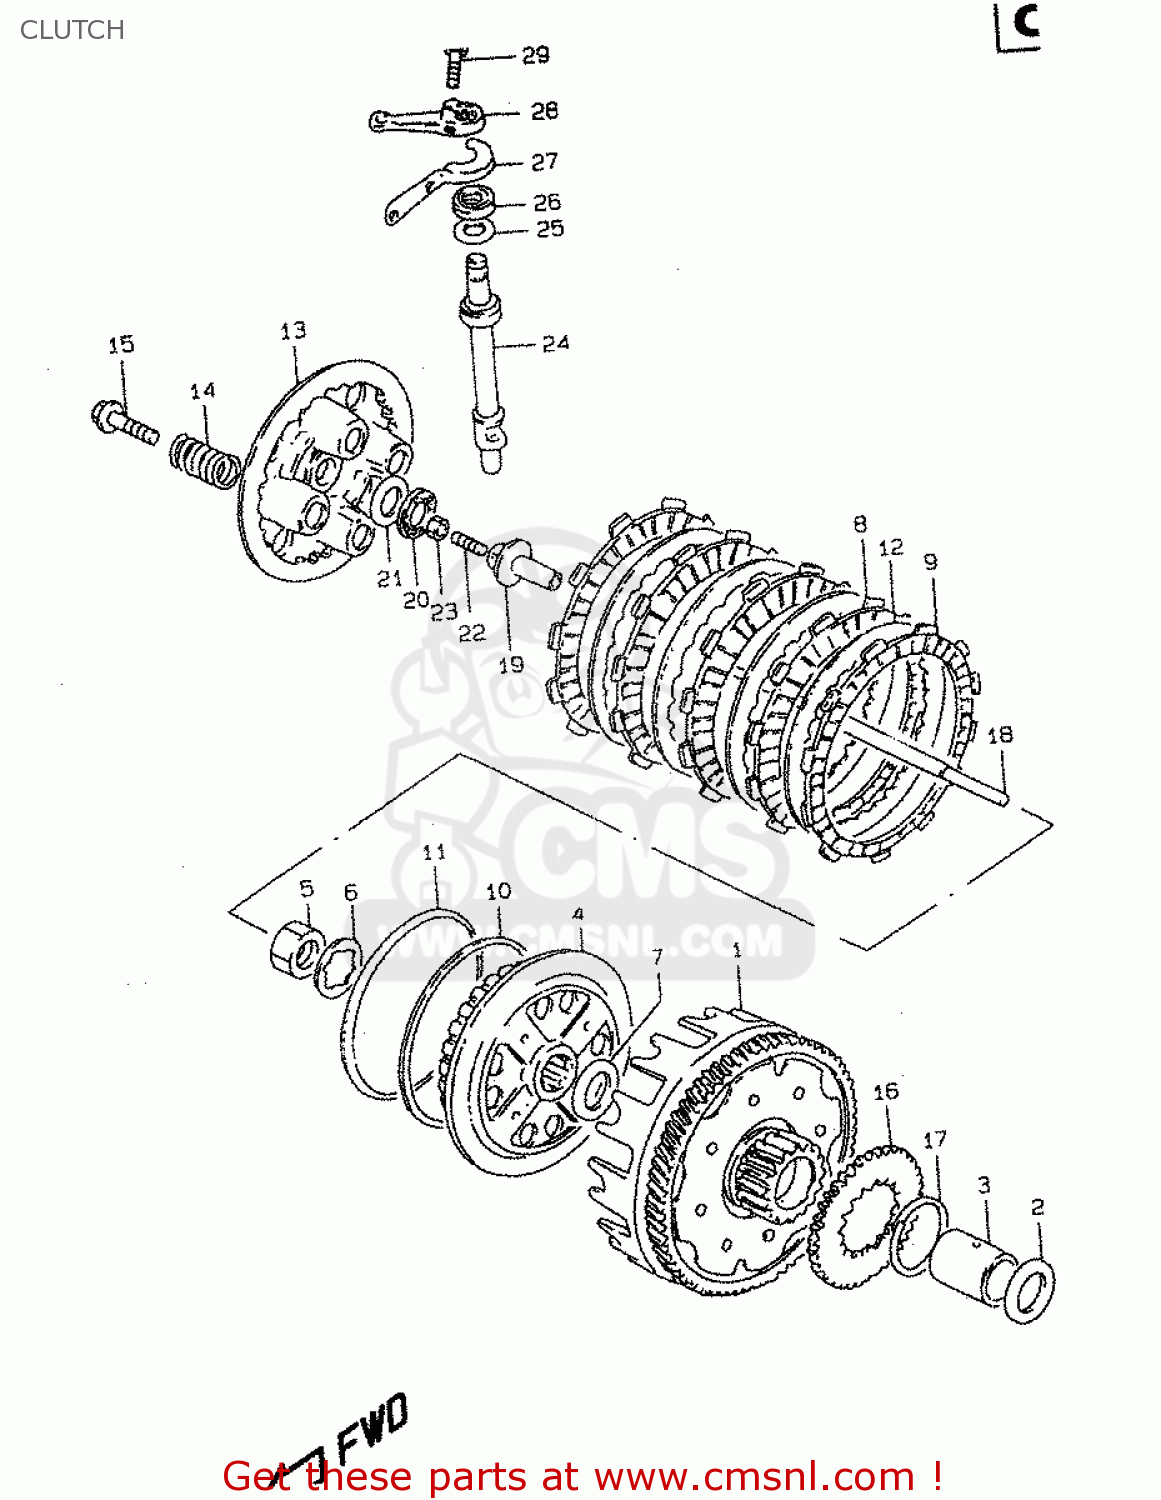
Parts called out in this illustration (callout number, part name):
1	GEAR ASSY,PRI DRIVEN
2	WASHER
3	SPACER(22X28X37.5)
4	HUB,CLUTCH SLEEVE
5	NUT
6	WASHER,LOCK
7	WASHER
8	PLATE,CLUTCH DRIVE (NAS)
9	PLATE,CLUTCH DRIVE(T:3.5) (NAS)
10	SEAT,WAVE WASHER(T:1.4)
11	WASHER
12	PLATE,CLUTCH DRIVEN(T:1.6) (NAS)
13	DISC,CLUTCH PRESSURE
14	SPRING,CLUTCH
15	BOLT(6X16)
16	GEAR,OIL PUMP DRIVE
17	CIRCLIP
18	ROD,CLUTCH PUSH
19	PIECE,CLUTCH PUSH
20	BEARING(15X28X2)
21	WASHER(15.5X28X1)
22	SCREW(6X25)
23	NUT
24	CAMSHAFT,CLUTCH RELEASE
25	WASHER(14.5X22X1)
26	OIL SEAL
27	PLATE,CLUTCH RRS CAMSHAFT SEAL
28	ARM,CLUTCH RELEASE
29	BOLT
